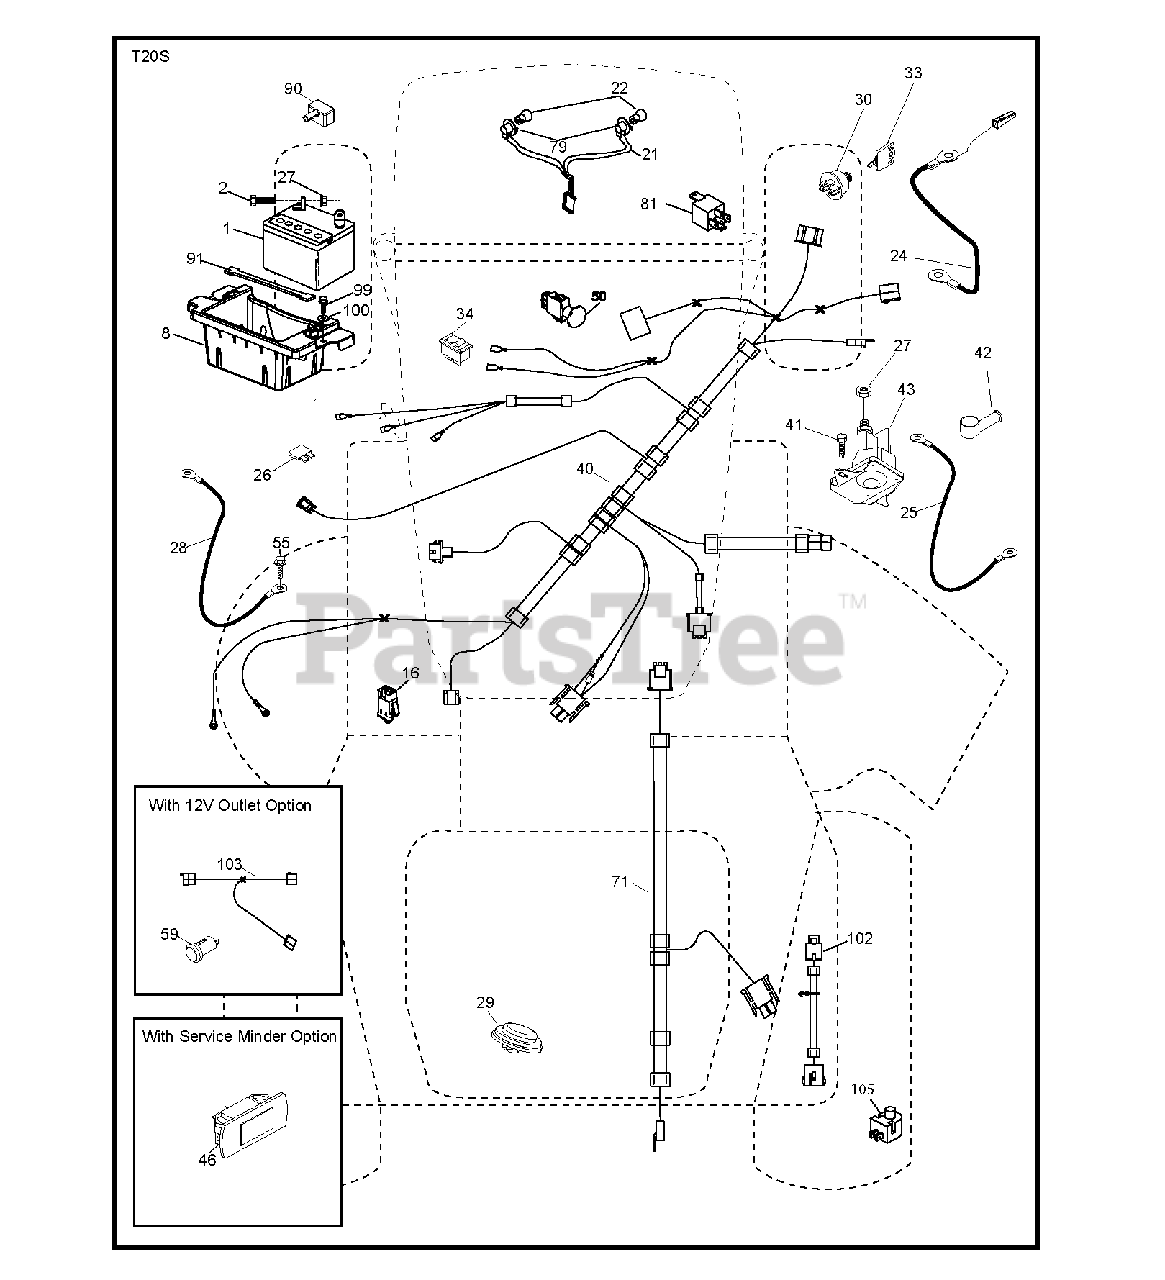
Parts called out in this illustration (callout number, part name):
1	REPL BY 532 12 38-99
8	BOX.BATTERY.MOUNT.FRONT.LT
16	SWITCH INTERLOOK PUSH-IN
21	HARNESS.LIGHT W/4152J BULBS
22	LIGHTBULB
24	CABLE.BATT.POS.WIRE.TG.DA SOL
25	CABLE.STARTER.6G.BL/RED.17.5
26	FUSE 20AMP
27	NUT
28	CABLE GROUND 6 GA 21" 90T BLK
29	SWITCH.SEAT.DELTA.OPC.
30	SWITCH.IGN.DELTA.W.LGH.ROS
33	KEY.CHAIN.BLISTER.PACK.GEN.USA
34	SWITCH LT
40	HARNESS.IGN.ELE.RELAY.TEX.46"
41	SCREW
42	TERMINAL COVER
43	SOLENOID.W/BRASS.PLUNG
46	GUAGE.SRVCMNDR.HRMTR.
50	PTO SWITCH
55	SCREW 5/16"
71	HARNESS-CHASSIS SUB
79	BULB HOLDER ASM.
81	RELAY HARNESS.SEALED
90	COVER.TERMINAL.BATTERY
91	STRAP, BATTERY MOUNT
99	SCREW HEXWSHR 1/4-20X3/4
102	HARNESS PIGTAIL PCH TEX ROS
105	REVERSE SWITCH
